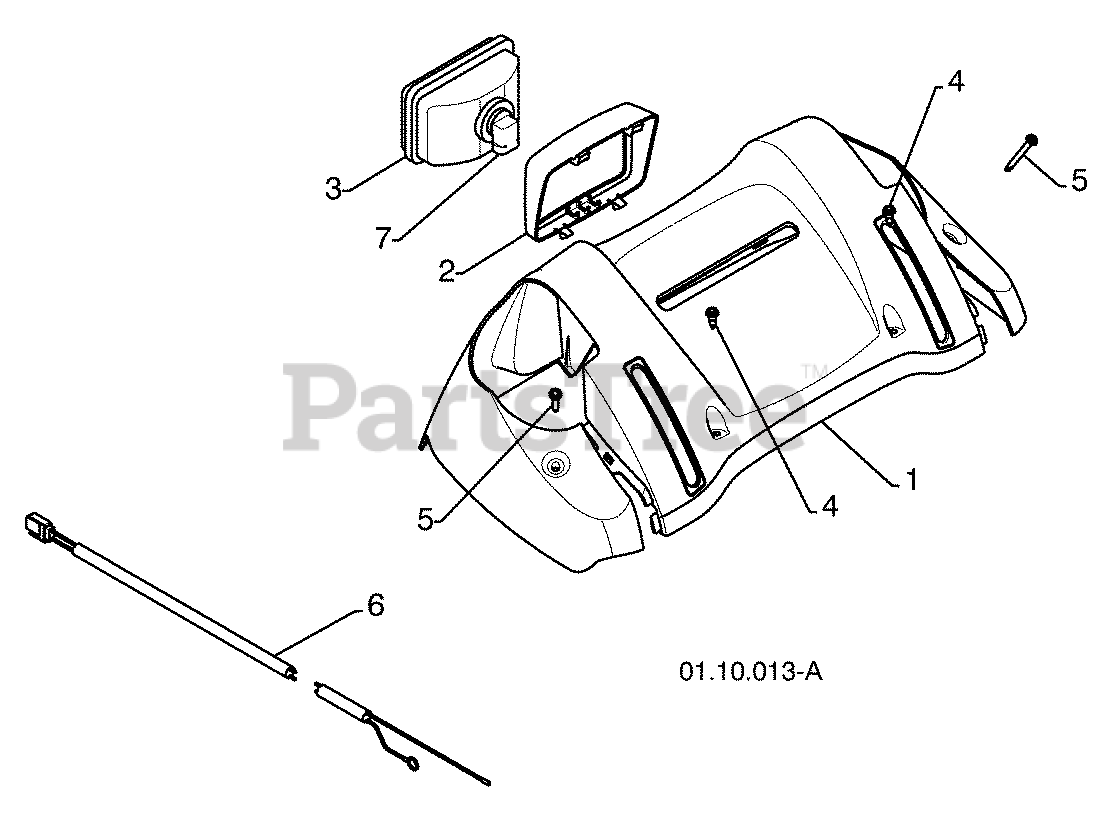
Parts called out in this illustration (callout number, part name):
1	PANEL CONSOLE GRAY
2	HEADLIGHT BEZEL GRAY
3	HALOGEN HEADLIGHT
4	SHOULDER SCREW
5	SCREW 10-24 X 1.25
6	WIRE HARNESS
